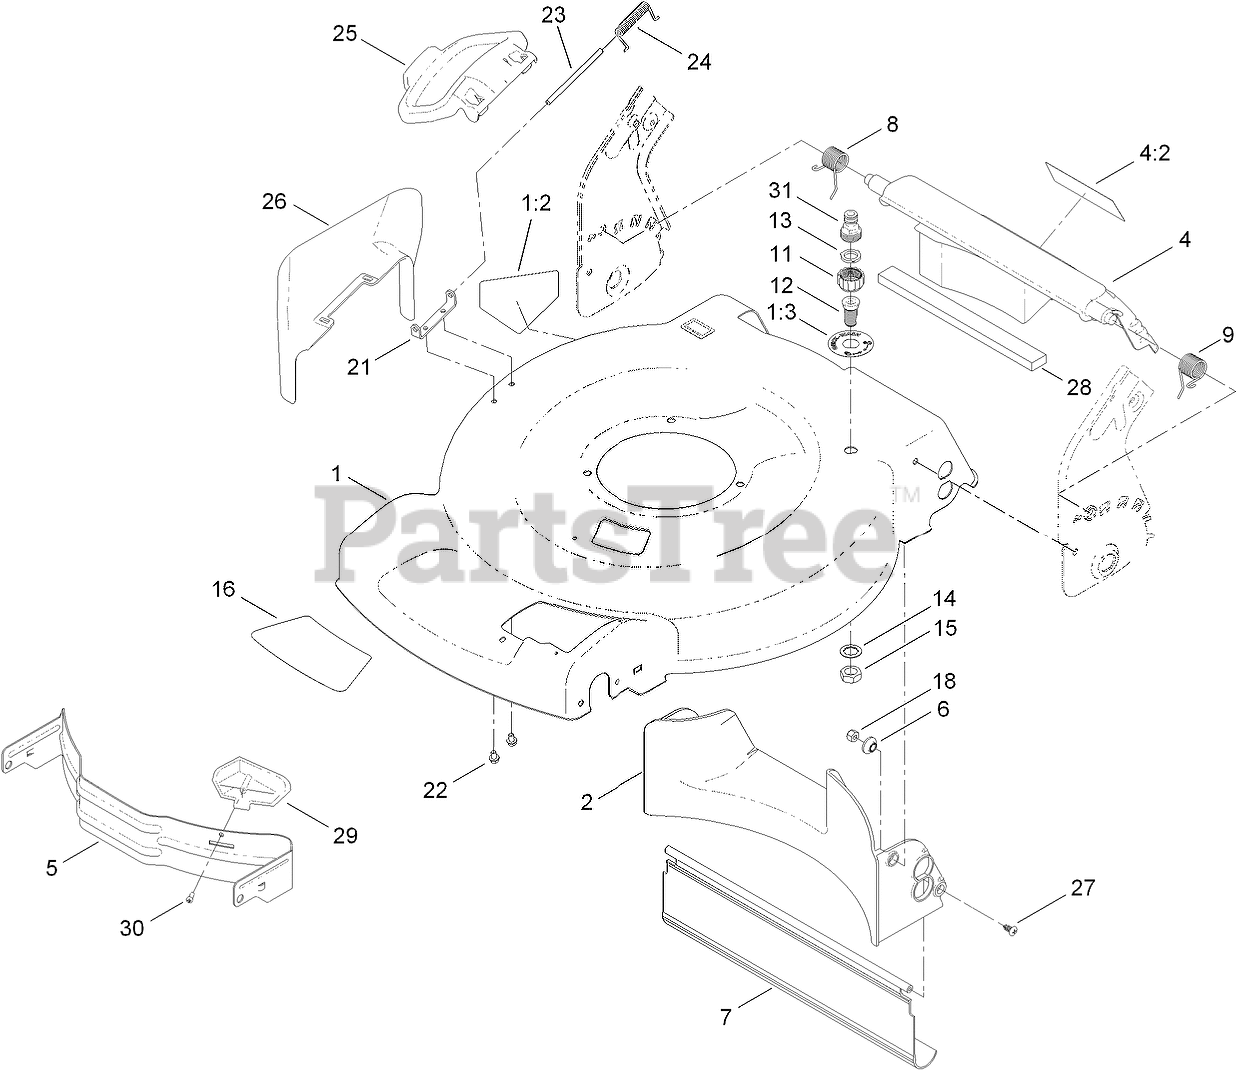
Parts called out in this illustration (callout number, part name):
1	HOUSING ASM
1:2	DECAL-DANGER
1:3	DECAL-PORT, WASHOUT
2	BAFFLE-REAR
4	REAR DEFLECTOR ASM
4:2	DECAL-WARNING
5	BAFFLE-FRONT
6	WASHER-STEPPED, BAFFLE
7	SHIELD-TRAILING
8	SPRING-TORSION
9	SPRING-TORSION
11	COUPLING-HOSE, WASHOUT PORT
12	PORT-WASHOUT
13	WASHER-SEAL, WASHOUT PORT
14	WASHER-TOOTH, INTERNAL
15	NUT-JAM
16	DECAL-DECK
18	NUT-LOCK, NI
21	BRACKET-COVER
22	SCREW-HWH
23	ROD-COVER
24	SPRING-TORSION
25	DEFLECTOR-SIDE
26	CHUTE-DISCHARGE, SIDE
27	SCREW-PTH
28	FOAM-SEAL
29	KICKER-FRONT
30	SCREW-PPH
31	ADAPTER-CONNECT, QUICK
